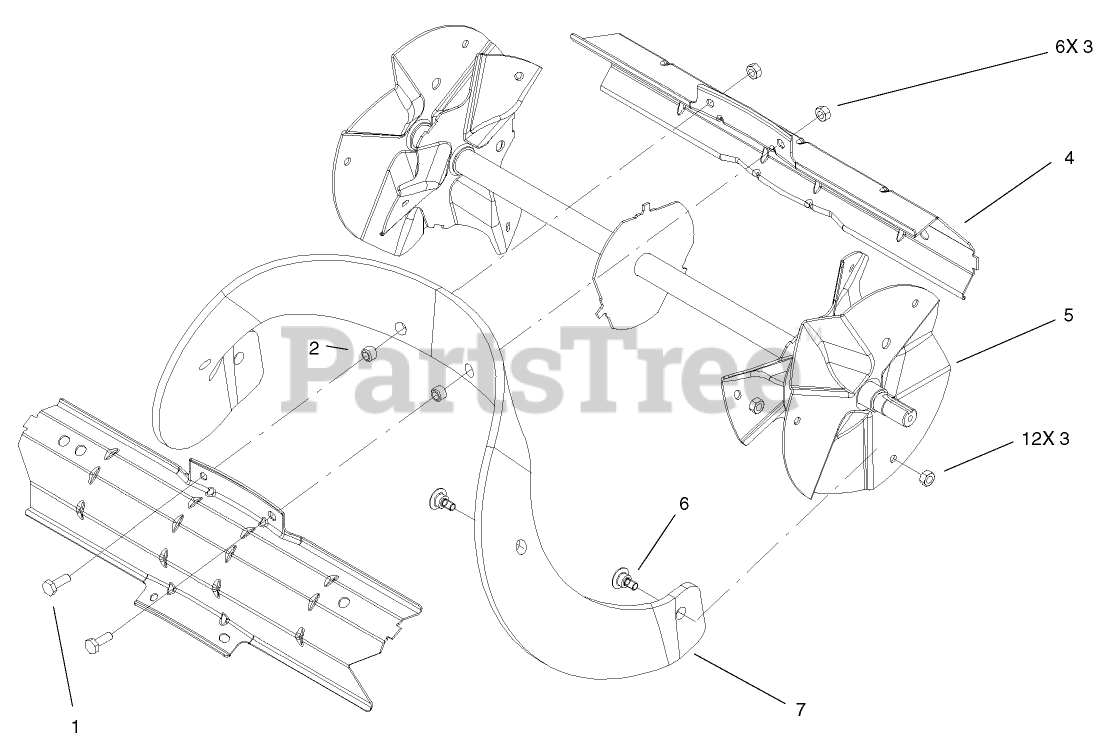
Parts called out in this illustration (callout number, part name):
1	SCREW-HH
2	SPACER-BLADE, ROTOR
3	NUT-LOCK, NI
4	DRUM-ROTOR
5	ROTOR ASM
6	SCREW
7	BLADE-ROTOR
